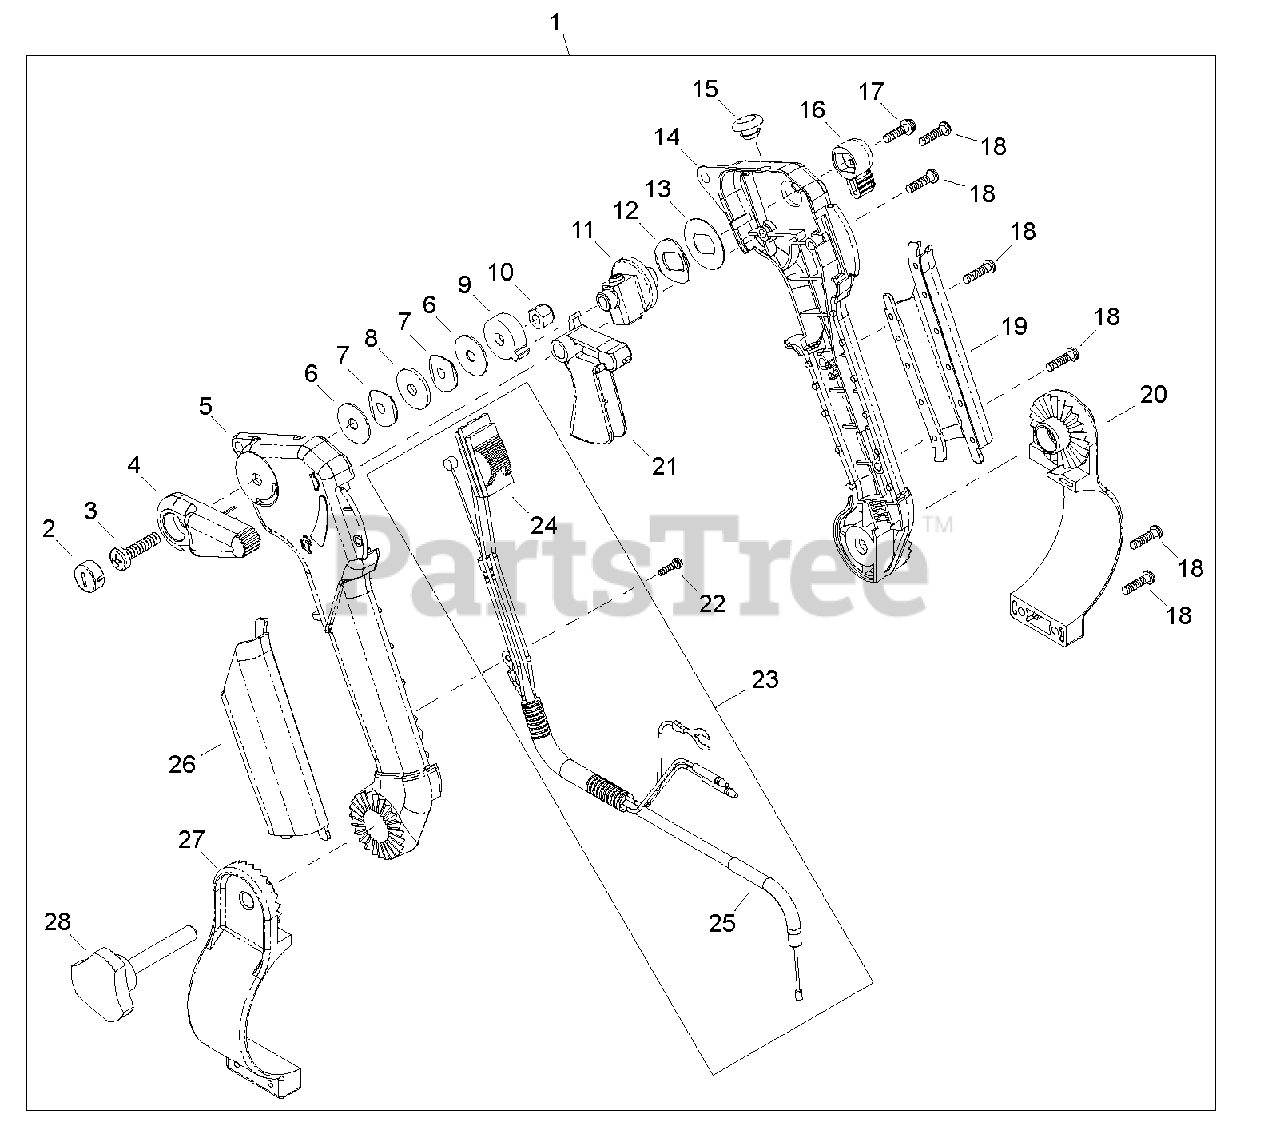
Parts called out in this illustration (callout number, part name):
1	THROTTLE LEVER ASSY
2	CRUISE CONTROL BOLT CAP
3	ADJUSTABLE BOLT
4	LEVER, LOCK
5	HANDLE, CONTROL - LEFT
6	WASHER - 6
7	LOCKWASHER
8	WASHER - 6
9	PLATE
10	NUT - 6 -- NYLON
11	ADJUSTER ASSY
12	WASHER - SPRING
13	WASHER
14	HANDLE, CONTROL - RIGHT
15	PLUG
16	SCREW, METERING LEVER PIN
17	SCREW, METERING LEVER PIN
18	SCREW
19	GRIP - RIGHT
20	BRACKET, HANDLE - RIGHT
21	TRIGGER, THROTTLE
22	SCREW - 3
23	THROTTLE CONTROL ASSY
24	SWITCH, IGNITION
25	CABLE, THROTTLE
26	GRIP - LEFT
27	BRACKET, HANDLE - LEFT
28	KNOB, FASTENER
